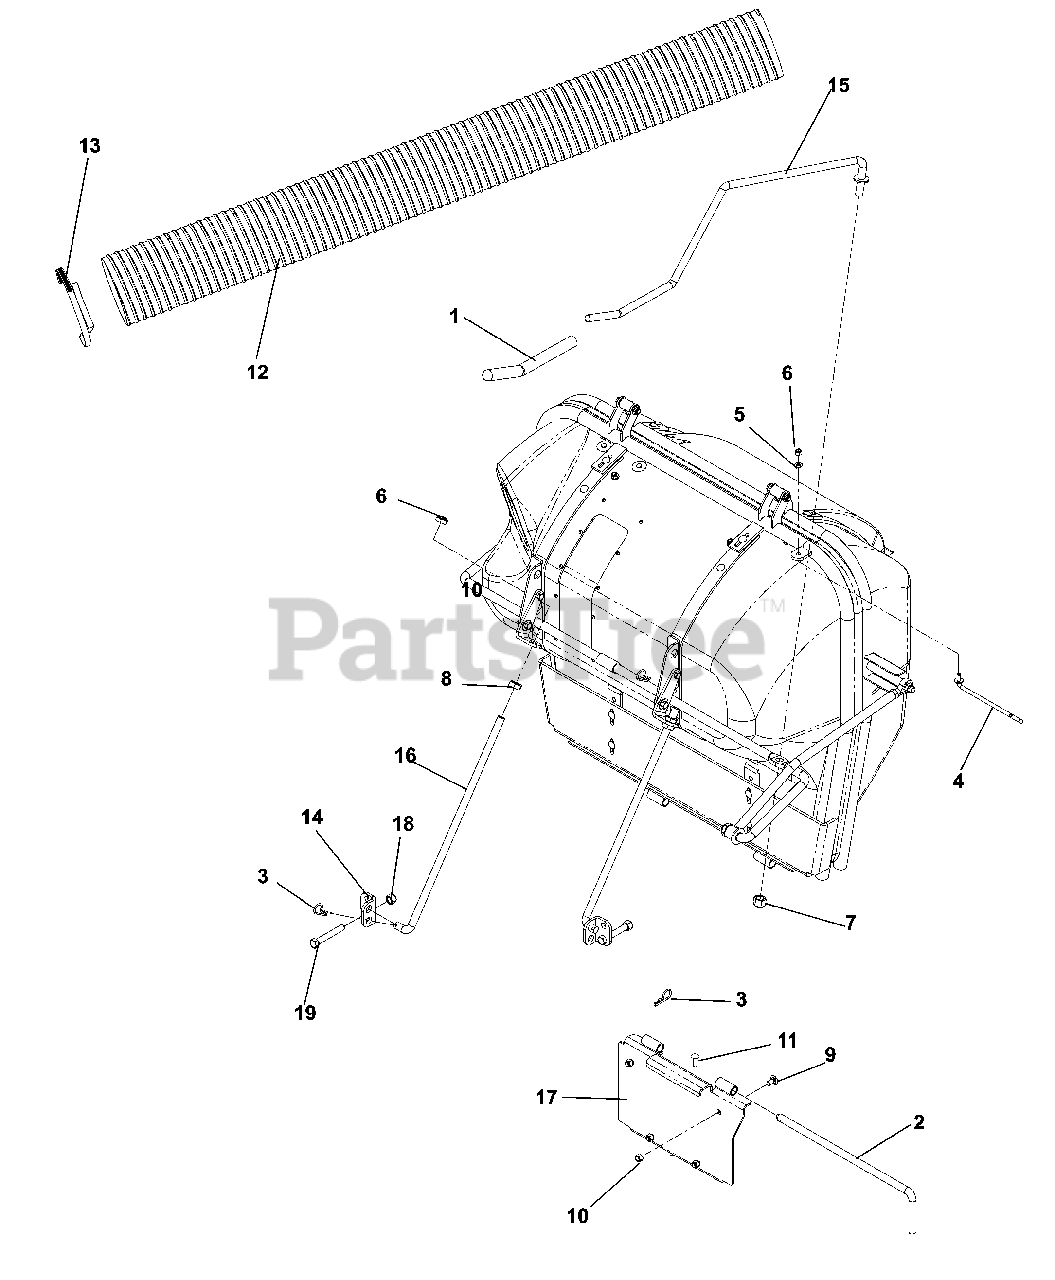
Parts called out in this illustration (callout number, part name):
1	BAR SLEEVE
2	HINGE PIN
3	PIN, COTTER 1 3/4
4	LINKAGE.LATCH
5	FLAT WASHER 5/16 SAE
6	NUT 5/16 NYLOC
7	NUT 5/8-11 NYLOC
8	NUT JAM 5/8-11 HEX
9	RHSNB 3/8-16 X 3/4 GR5 ZD
10	NUT 3/8-16 NYLOC
11	RHSSNB 5/16C X 1.0
12	FLEX HOSE 6 X 60
13	HOSE CLAMP
14	BRACKET, SUPPORT
15	DUMP ARM, KODIAK
16	LINKAGE, SUPPORT
17	PLATE, MOUNT, LOWER
18	NUT 1/2-13 HEX NYLOC ZD
19	HCS 1/2C X 3 1/4
